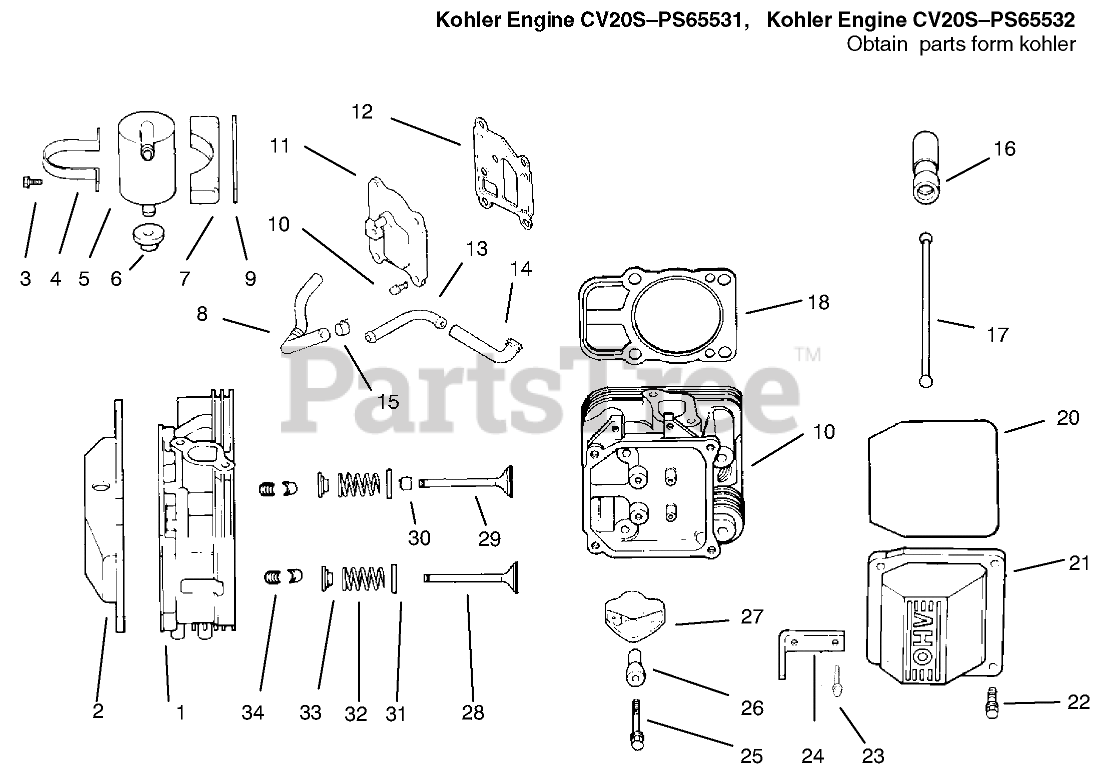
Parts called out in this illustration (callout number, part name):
1	#1 Cyl. Head Asm
2	Cover-Rocker
3	Kit-Breather INC 4
4	Grommet-Rubber
5	Cover-Breather
6	Screw
7	Hose-Breather
8	Retainer Kit
9	Cap-Spring, Valve
10	Spring-Valve
11	Retainer-Spring
12	Valve-Exhaust
13	Valve-Intake
14	Seal-Stem, Valve
15	Fitting
16	Hose-Breather
17	Lifter-Valve
18	Rod-Push
19	Gasket-Cylinder Head
20	#2 Cyl. Head Asm,
21	Arm-Rocker
22	Pivot-Rocker Arm
24	Cover-Rocker
25	Screw
26	Screw
27	Strap-Lifting
